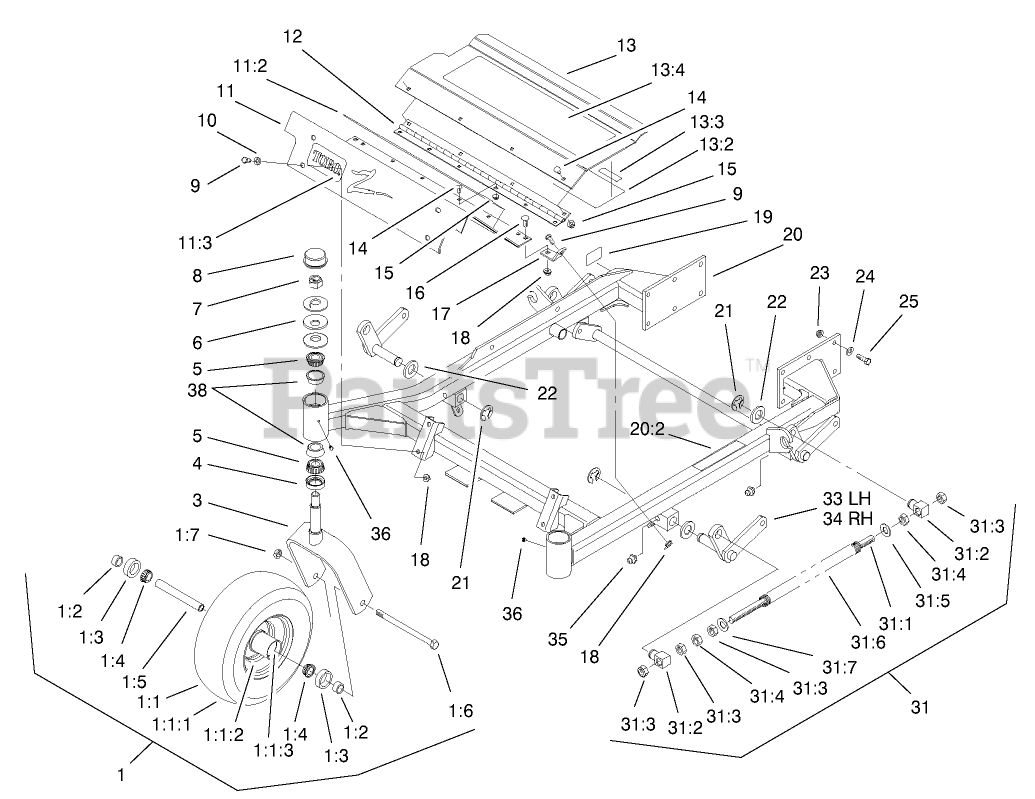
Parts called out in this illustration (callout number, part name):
1	CASTER WHEEL ASM
1:1	WHEEL and TIRE ASM
1:1:3	BEARING-CUP
1:2	SPACER-BEARING
1:3	SEAL-BEARING
1:4	BEARING-CONE, TAPER
1:5	SPACER-CASTER, FRONT
1:6	SCREW-HH
1:7	NUT-LOCK, NI
3	CASTER
4	SEAL-GREASE
5	BEARING-CONE, TAPERED
6	WASHER-BELLVILLE
7	NUT-LOCK, NI
8	CAP-GREASE
9	SCREW-HH
10	WASHER-PLAIN
11	FLOORPAN-FRONT
11:2	PAD-ANTISKID
12	HINGE-FLOORPAN
13	FOOTREST ASM
13:2	DECAL-SERVICE
13:3	DECAL-COVER, MISSING
13:4	PAD-ANTISKID
14	SCREW-CARR
15	NUT-HF
16	BOLT-CARR
17	BRACKET-FLOORPAN
18	NUT-HF
19	DECAL-STD, SAFETY
20	FRONT FRAME ASM
20:2	DECAL-WARNING
21	RING-RETAINING, EXT
22	WASHER-FLAT
23	NUT-HHF, WHIZ
24	WASHER-BELLEVILLE
25	SCREW-HH
31	Front Spring ASM
31:1	ROD-LIFT, DECK
31:2	SWIVEL-DECK MOUNT, REAR
31:3	NUT-HEX
31:4	NUT-JAM
31:5	Washer
31:6	SPRING-COMPRESSION
31:7	WASHER-FLAT
33	LH LIFT ARM ASM
34	RH LIFT ARM ASM
35	FITTING-GREASE
38	BEARING-CUP, TAPERED
